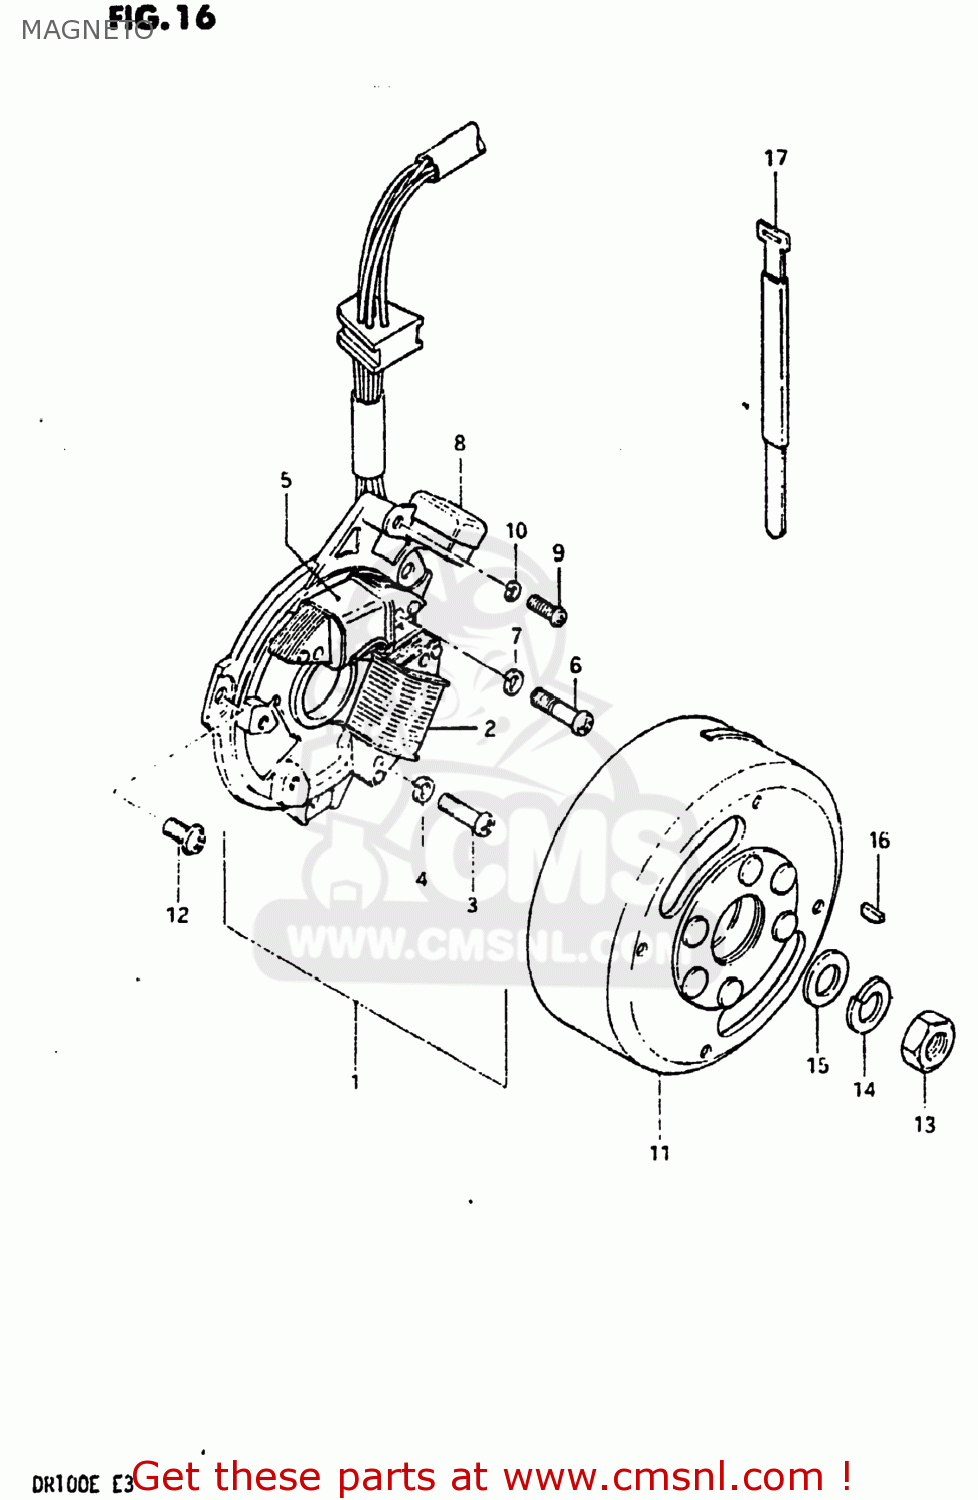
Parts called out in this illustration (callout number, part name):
1	STARTER ASSY
2	COIL,LIGHTING
3	SCREW
4	LOCK WASHER
5	COIL,IGNITION PRIMARY
6	SCREW
7	LOCK WASHER
8	COIL
9	SCREW
10	LOCK WASHER
11	ROTOR ASSEMBLY
12	SCREW(5X14)
13	NUT (10MM)
14	LOCK WASHER
15	WASHER
16	KEY
17	CLAMP L:110
